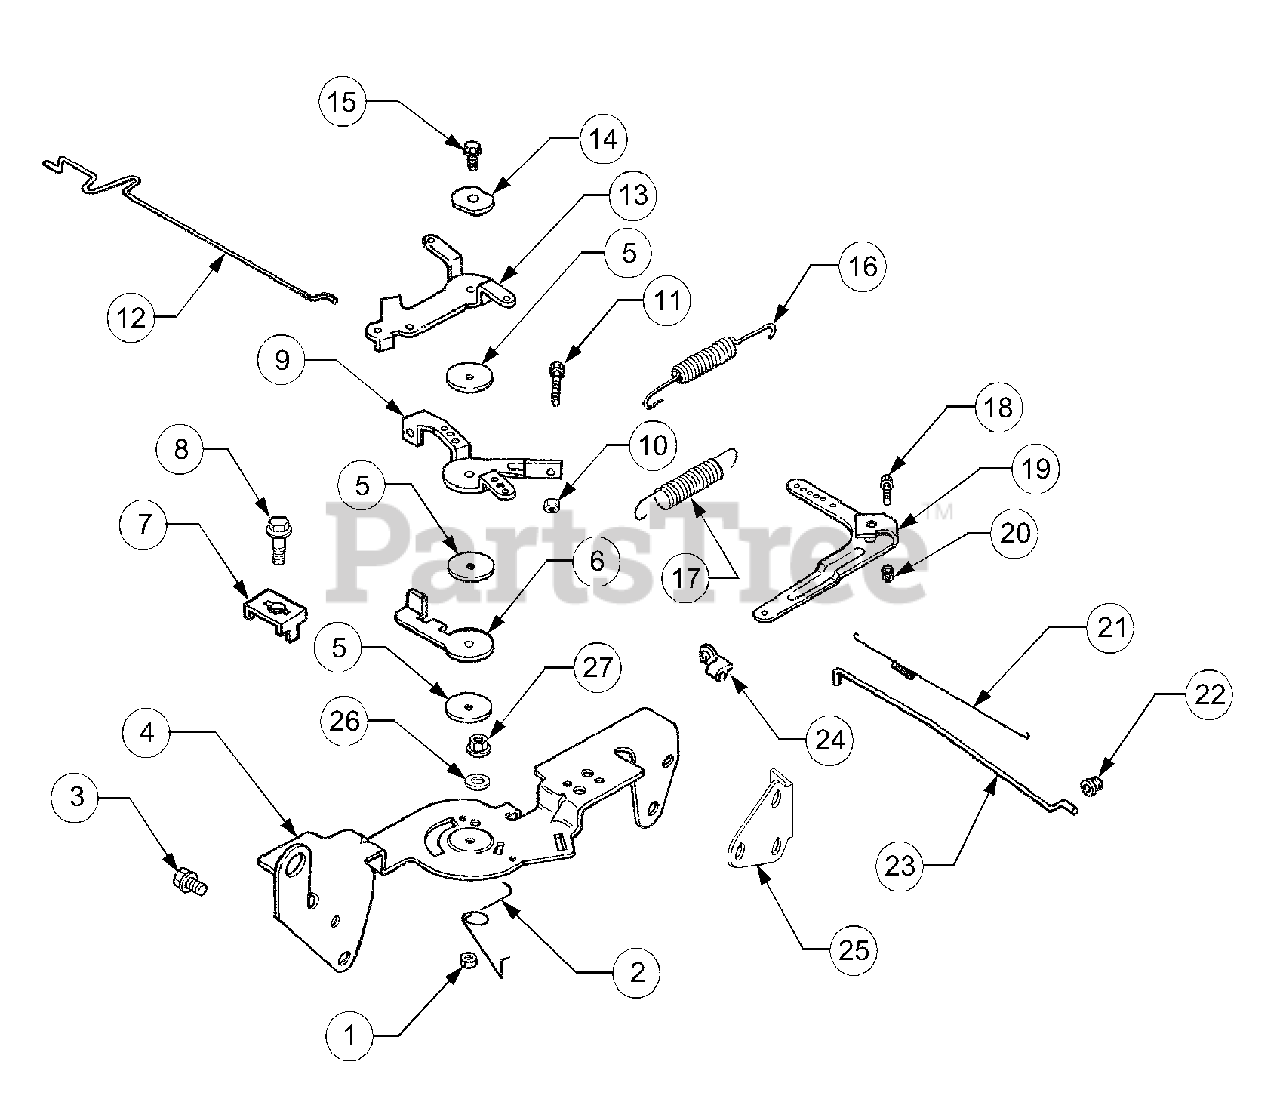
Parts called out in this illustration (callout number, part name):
1	Nut, Hex Lock M5 x 0.8
2	Spring, Choke Return
3	Screw, Hex Flange M6 x 1.0 x 16
4	Bracket, Control
5	Washer , Plain 5.5mm
6	Lever, Throttle Actuator
7	Clamp, Cable
8	Screw, Hex Flange M5 x 0.8 x 16
9	Lever, Throttle Control
10	Nut, Hex M4 x 0.7
11	Screw, Hex Cap M4 x 0.7 x30
12	Linkage, Choke
13	Lever, Choke
14	Washer, Spring 1/4"
15	Screw, Hex Flange M5 x 0,.8 x 20
16	Spring, Throttle Limiter
17	Spring, Governor
18	Screw, Round Hd. Square Neck
19	Lever, Governor
20	Nut, Hex Flange M6 x 1.0
21	Spring, Linkage
22	Bushing, Linkage Retaining
23	Linkage, Throttle
24	Bushing, Linkage Retaining
25	Bracket, Support
